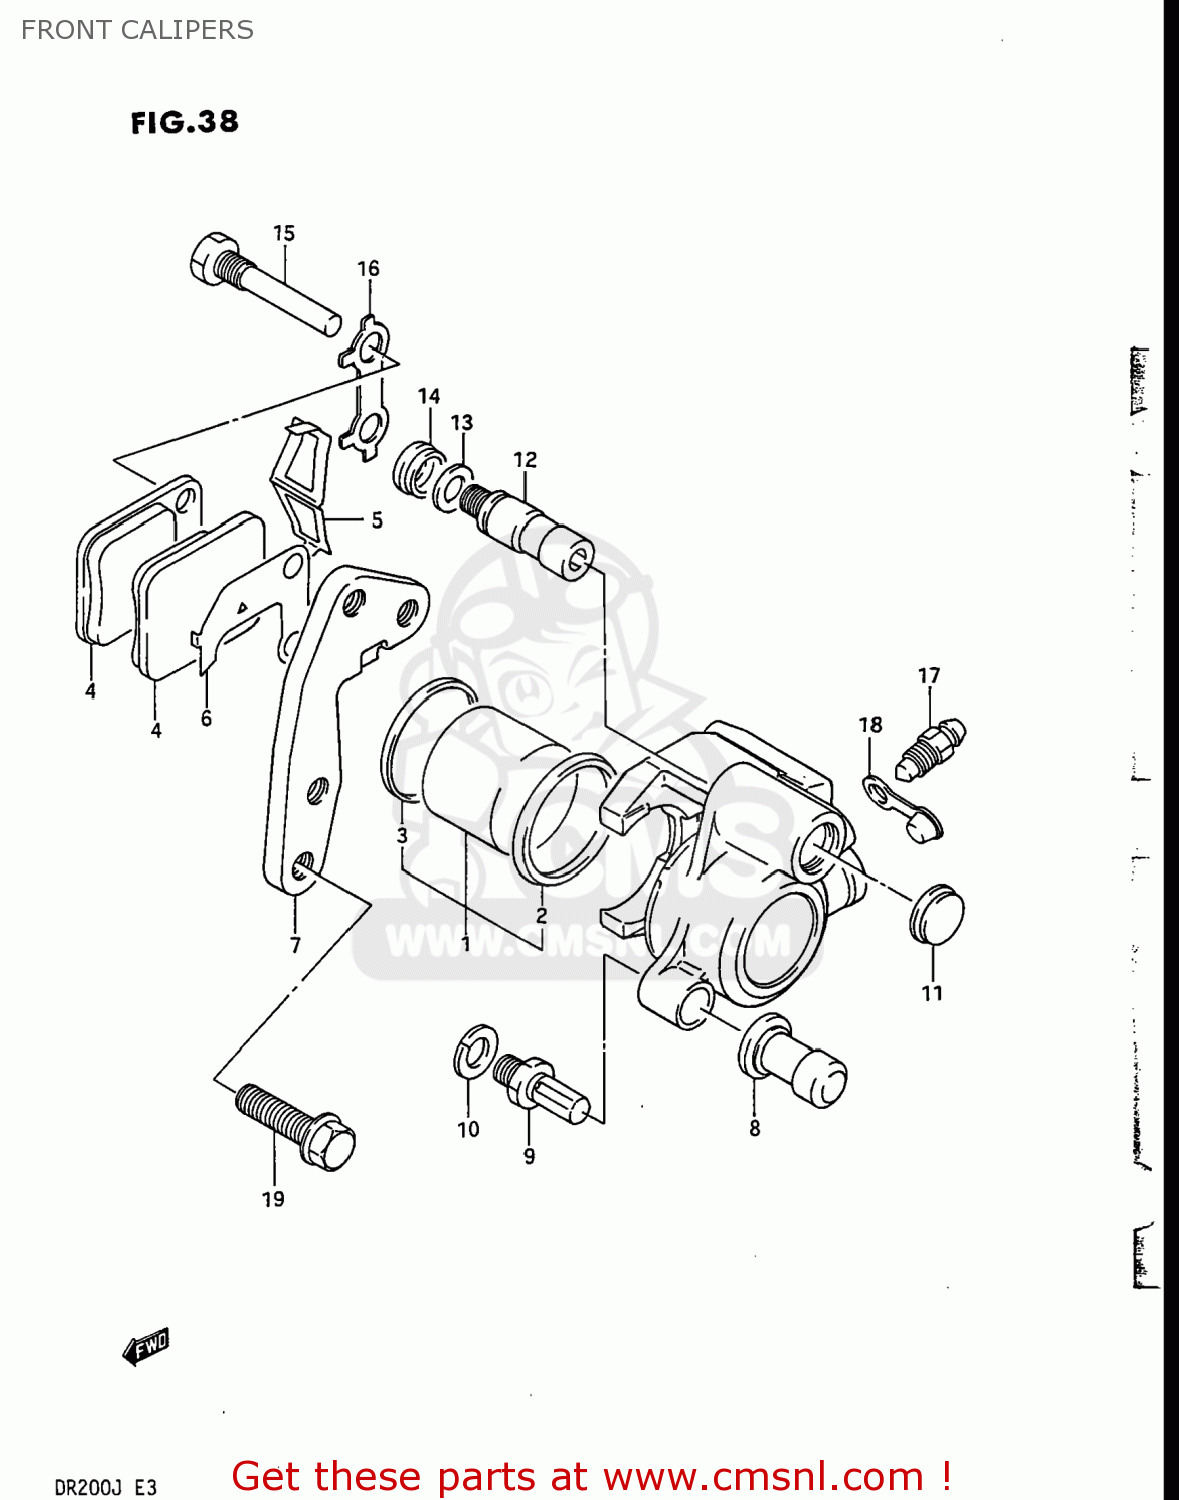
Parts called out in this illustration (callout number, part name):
1	PISTON SET,CALIPERS
2	SEAL,PISTON
3	BOOT,PISTON
4	PAD
5	SPRING,PAD
6	SHIM
7	BRACKET
8	BOOT
9	BOLT,PIN
10	WASHER,WAVE
11	DUST SEAL
12	PIN,SLIDE
13	SPRING,FRICTION
14	BOOT,PIN
15	PIN,HANGER
16	WASHER
17	BLEEDER
18	CAP,BLEEDER
19	BOLT 8X30
